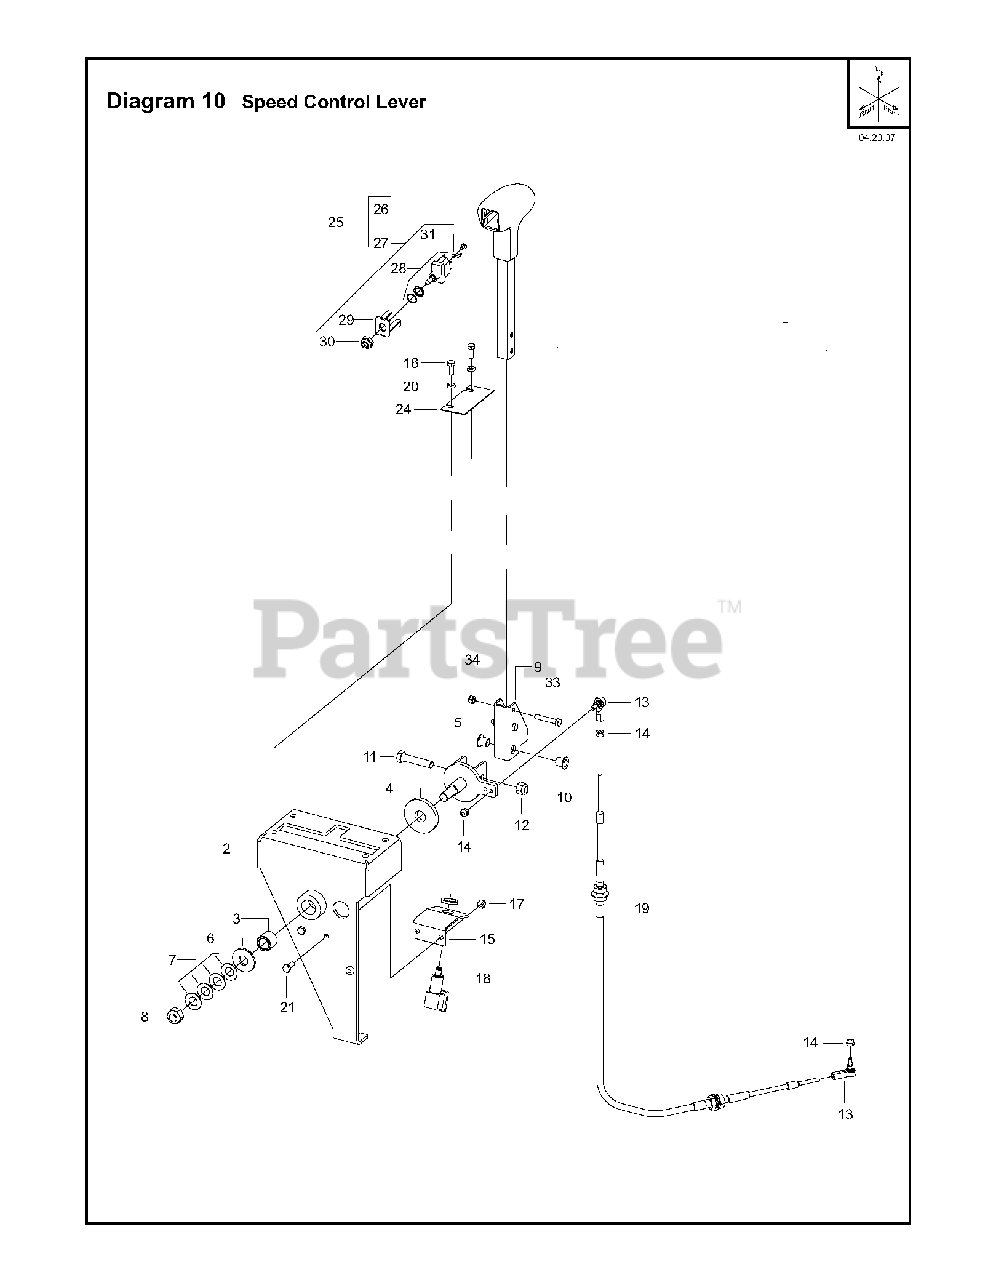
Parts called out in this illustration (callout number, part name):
1	SPEED CONTROL LEVER ASSY-BASIC
2	SPEED CONTROL: SHIFT Z/P
4	DECAL
5	ARM. SHIFTER PIVOT Z/P
8	LOCKNUT. FIBER M12 DIN 985 Z/P
9	SHIFT PIVOT POINT: Z/P
11	HHCS. .375-16 SPECIAL
12	LOCKNUT. FIBER .375-16 Z/P
14	LOCKNUT. #10 - 32
15	SWITCH: NEUTRAL SAFETY BR Z/P
16	HHCS. M6 x 1.0 x 16 DIN933 Z/P
17	LOCKNUT. FIBER M6 DIN 985
18	NEUTRAL SAFETY START SWITCH
20	LOCKWASHER. SPLIT M6
21	HHCS. M6 x 1.0 x 16 DIN933 Z/P
22	WASHER
23	LOCKNUT. #10 - 32
24	KIT.WHEEL.HD.RH.16'.GRY
25	HANDLE & SWITCH ASSY
26	TBDHandle Tube / Grip Assy
30	BOOT. HALF-TOGGLE SWITCH
31	TERMINAL LUG. SOLDER
33	HHCS. M6 x 1.0 x 35 DIN931 Z/P
34	LOCKNUT. FIBER M6 DIN 985
